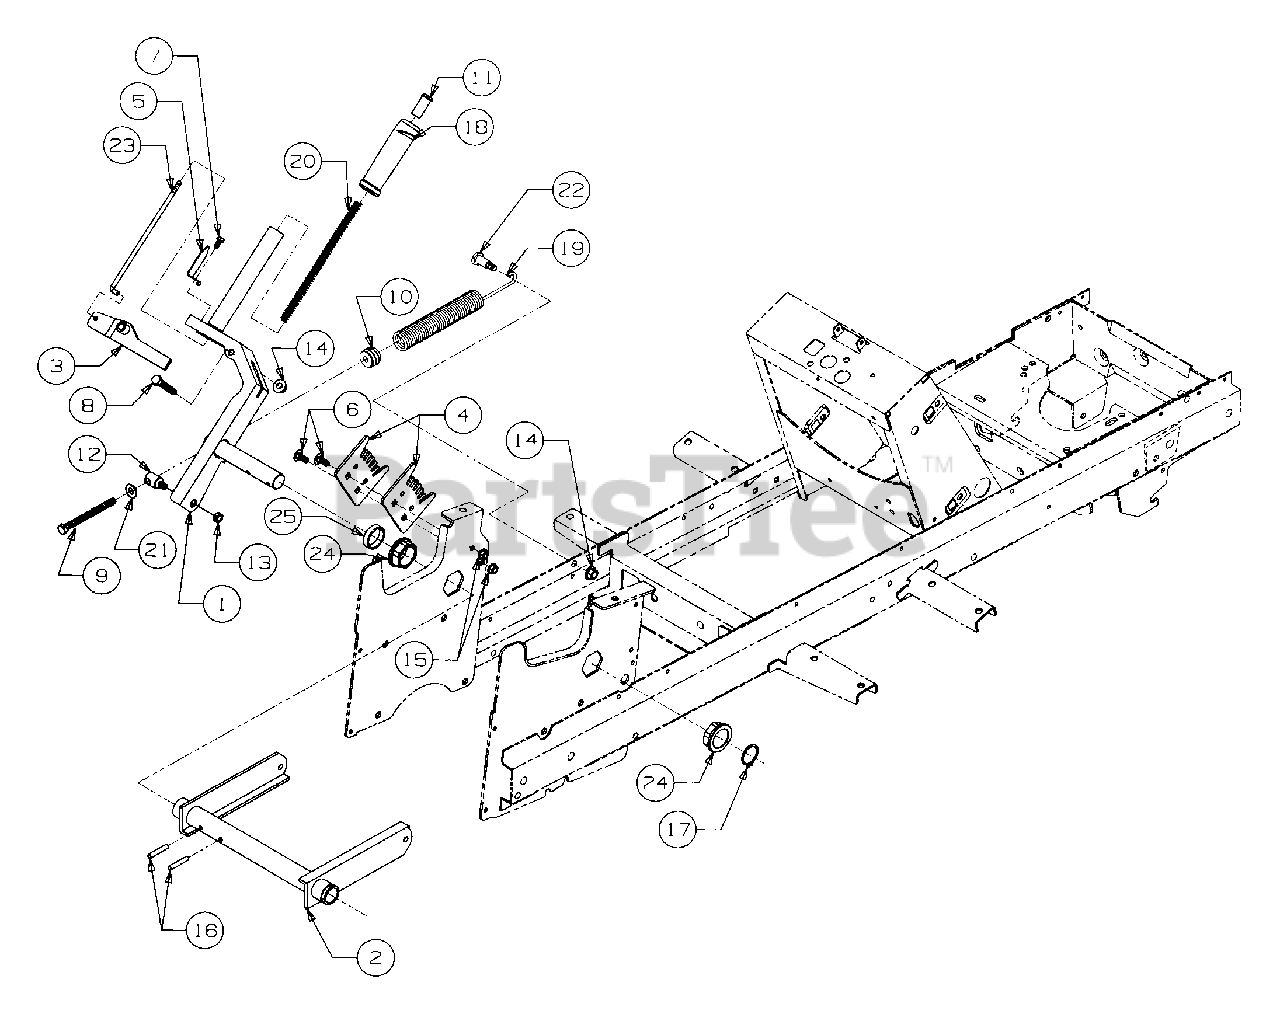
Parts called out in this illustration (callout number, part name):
1	Handle Assembly, Lift
2	Shaft Assembly, Lift
3	Fork, Lift
4	Bracket, Lift Index
5	Indicator, Lift Height
6	Bolt, Carriage, 5/16-18 x .75
7	Screw, Hex Wash Tapp, 1/4 x .5
8	Screw, Hex Cap, 3/8-16 x 2 GR5
9	Screw, Cap, 3/8-16 x 4.25 GR5
10	Insert, Spring
11	Button, Handle
12	Ferrule, Adjustment
13	Nut Center Lock Jam 3/8-24
14	Nut, Hex Flanged Lock, 3/8-16
15	Nut, Flanged Top Lock, 5/16-18
16	Pin, Spiral Spring, 1/4 Dia x 1.5
17	Ring, Snap, 1.25 Dia Shaft
18	Grip, Lift Handle
19	Spring, Extension
20	Spring, Compression
21	Washer, Flat, .385 x .87 x .06
22	Bolt, Shoulder
23	Rod, Index
24	Bearing, Hex Flange, 1.25 ID
25	Spacer, 1.28 ID x 1.5 OD x .335
